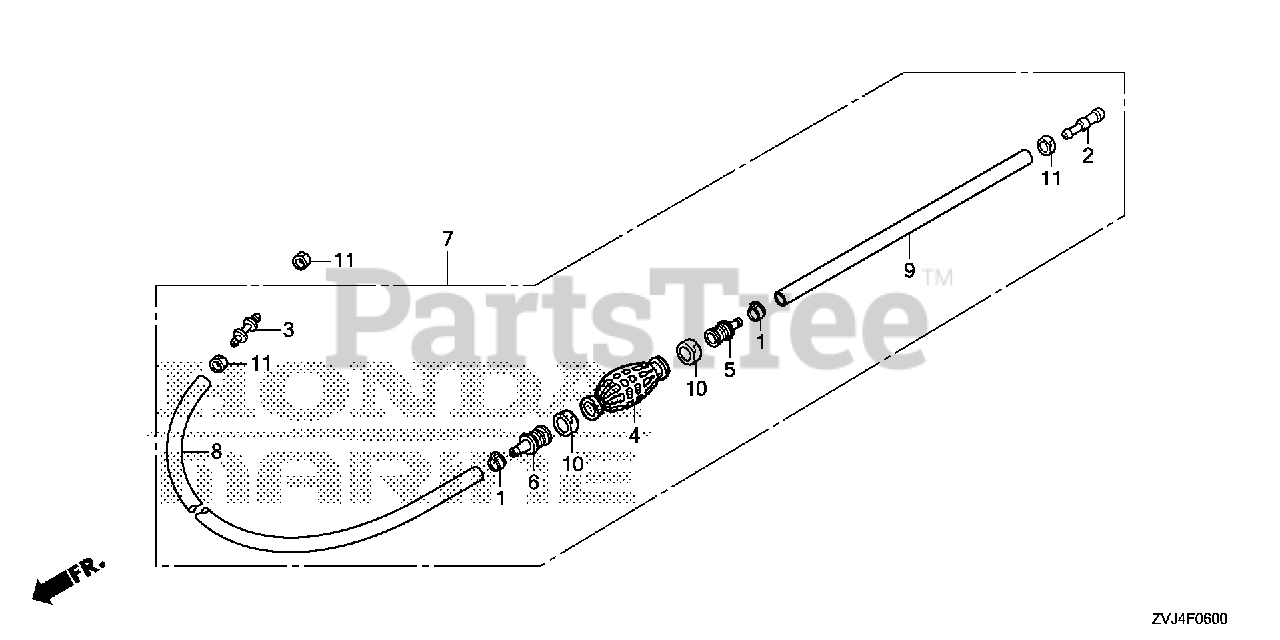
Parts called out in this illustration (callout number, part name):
1	CLAMP, FUEL TUBE (14.0)
2	JOINT, FUEL TUBE
3	JOINT, FUEL TUBE
4	BULB, PRIMER
5	VALVE, IN.
6	VALVE, OUTLET
7	TUBE ASSY., FUEL TANK
8	TUBE, FUEL LONG (7.3X2000)
9	TUBE, FUEL SHORT
10	BAND, TUBE CLIP (20MM)
11	BAND, TUBE CLIP (12.5MM)
